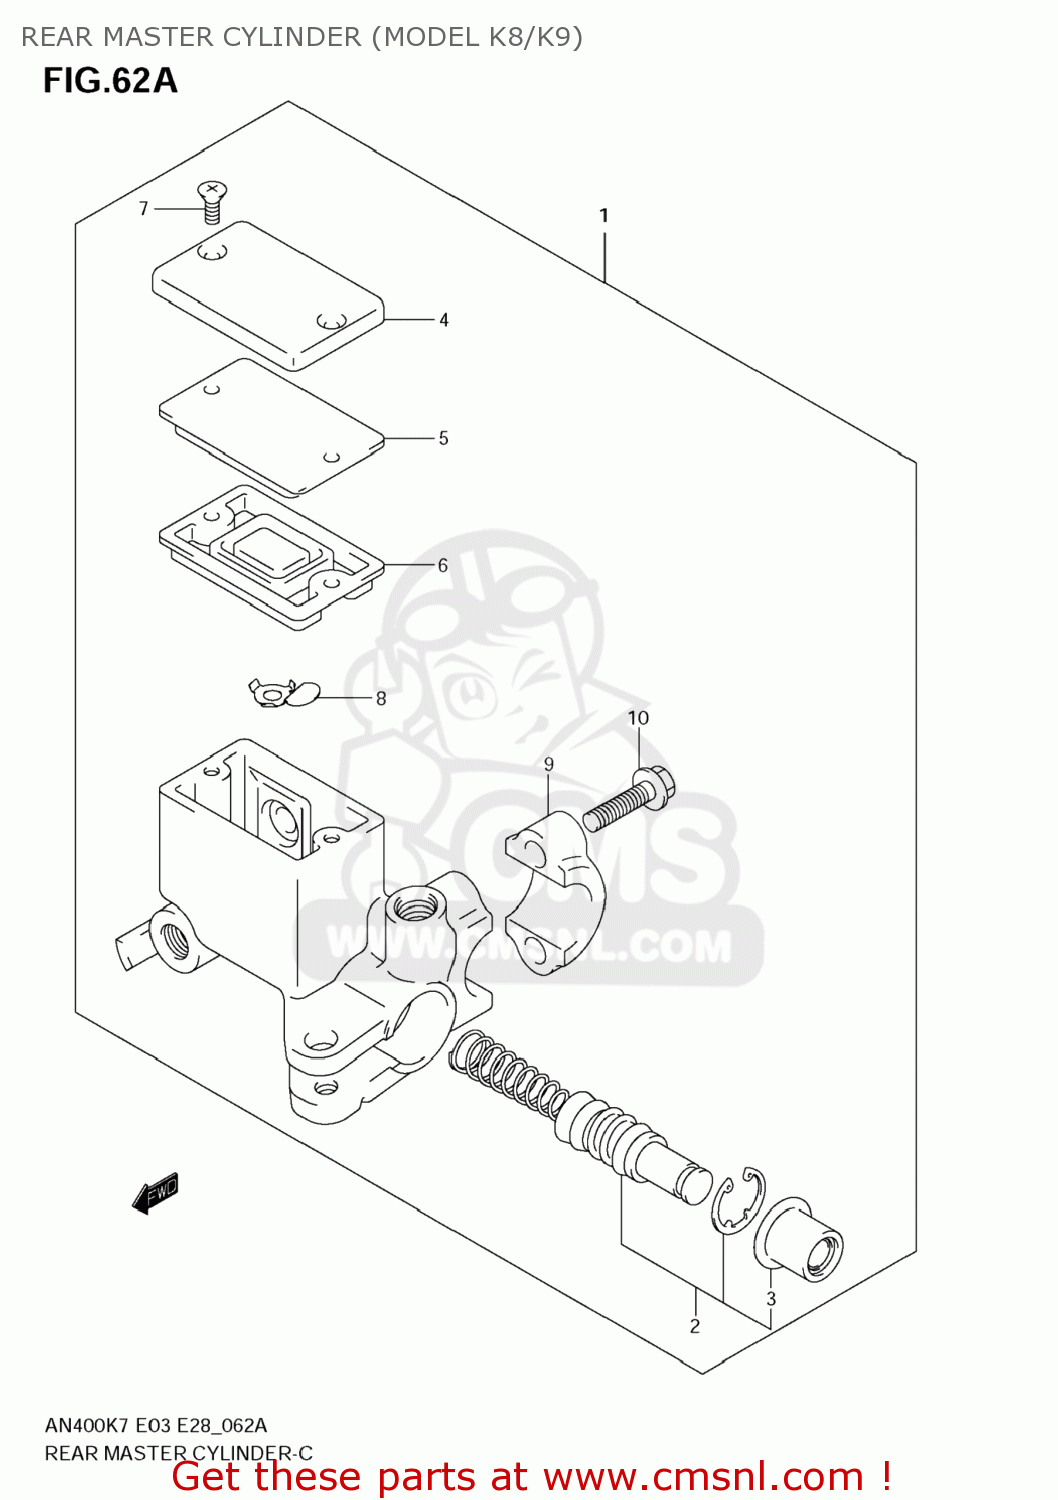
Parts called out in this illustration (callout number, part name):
1	CYLINDER ASSY,RR MASTER
2	PISTON/CUP SET
3	BOOT
4	CAP
5	PLATE,DIAPHRAGM
6	DIAPHRAGM
7	SCREW
8	PROTECTOR
9	HOLDER
10	BOLT(6X22)
